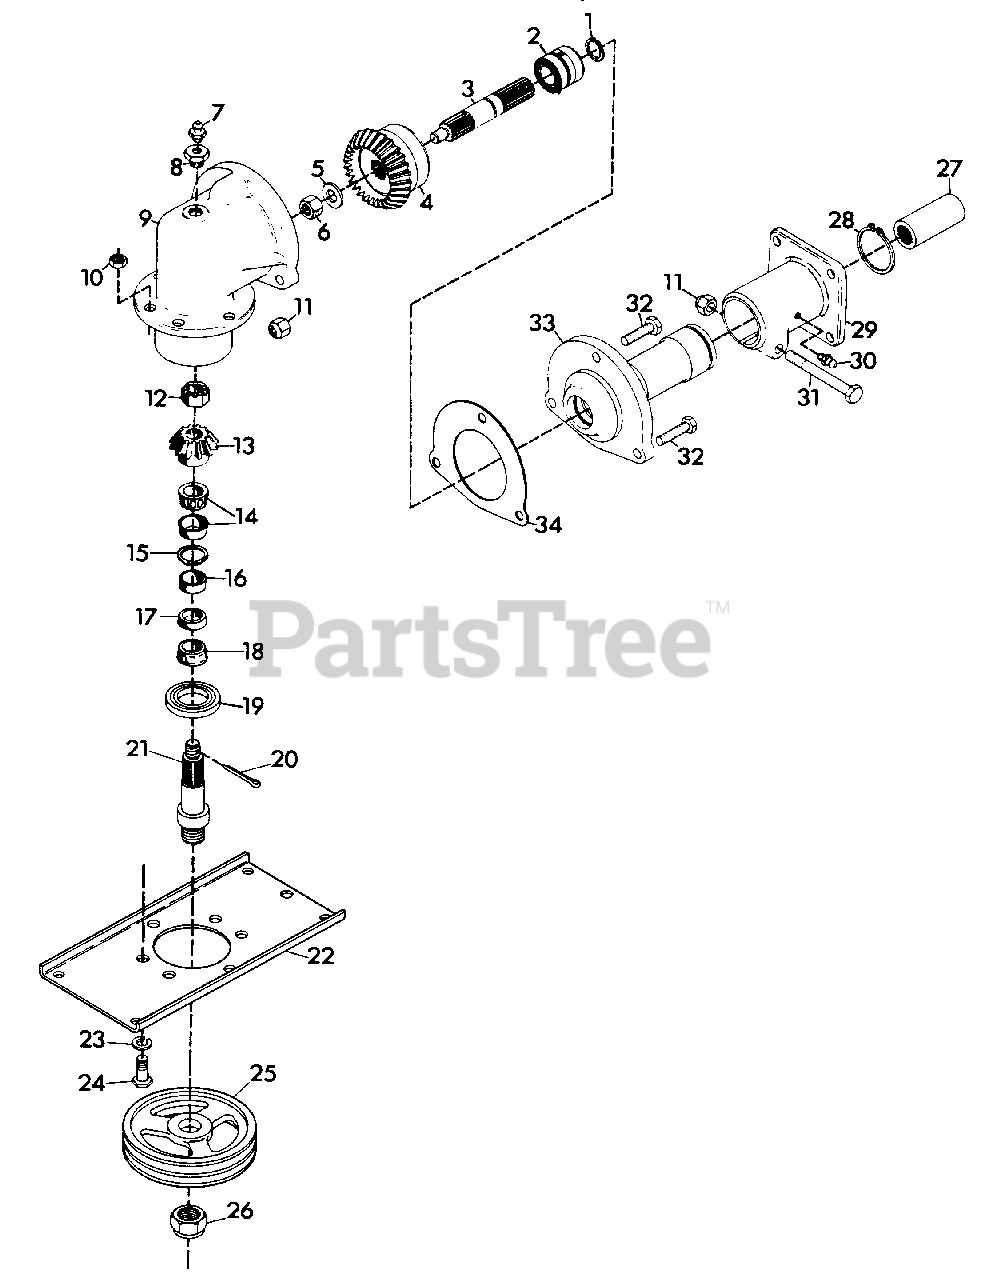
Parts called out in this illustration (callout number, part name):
1	RG-RTNG .937SHAFT
2	BRG-ASM 1.000X1.980X1.243
3	SHFT,DRIVE
4	GR,BEVEL
5	WSHR-FL-STL .687X1.312X.15 YWZ
6	NUT-LK-NYL .625-18 YWZC
7	FITTING, LUBE 1/8 NPT
8	BUSH .50 REDUCING PIPE
9	HOUSING,GEAR
10	NUT-JAM .50-13 YWZC
11	NUT-LK-NYL .50-13 YWZC
12	NUT-HEX-SL .625-18 YWZC
13	GR,BEVEL PINION
14	ASM,BEARING CUP&CONE
15	RG-RTNG-INT 2.210X.062
16	BUSH.,S1.75X1.94X.445 ST
17	BRG-CUP 1.980X.420
18	BRG-CONE 29MMX.58
19	SEAL 1.345X2.441X.312
20	PIN-CTR EXTPRSQCT .09X1.25 YZ
21	SHFT,ROTOR
22	PLT,MOUNTING
23	WSHR-LK .50X.125 REG YWZC
24	BOLT, HEX SPECIAL
25	SHEAVE,1/2X6 DBL GROOVE
26	NUT-SPECIAL 1.0-14X.406
27	CPLG,
28	RG-RTNG-EXT 2.250X.078
29	CSTG,SWIVEL
30	FTG,LUBE, .25-28 SELF THREAD
31	BLT-HEX .50-13X3.25 GR5 YWZC
32	BLT-HEX .50-13X1.75 GR5 YWZC
33	HSG,SHAFT
34	SHIM,.005
